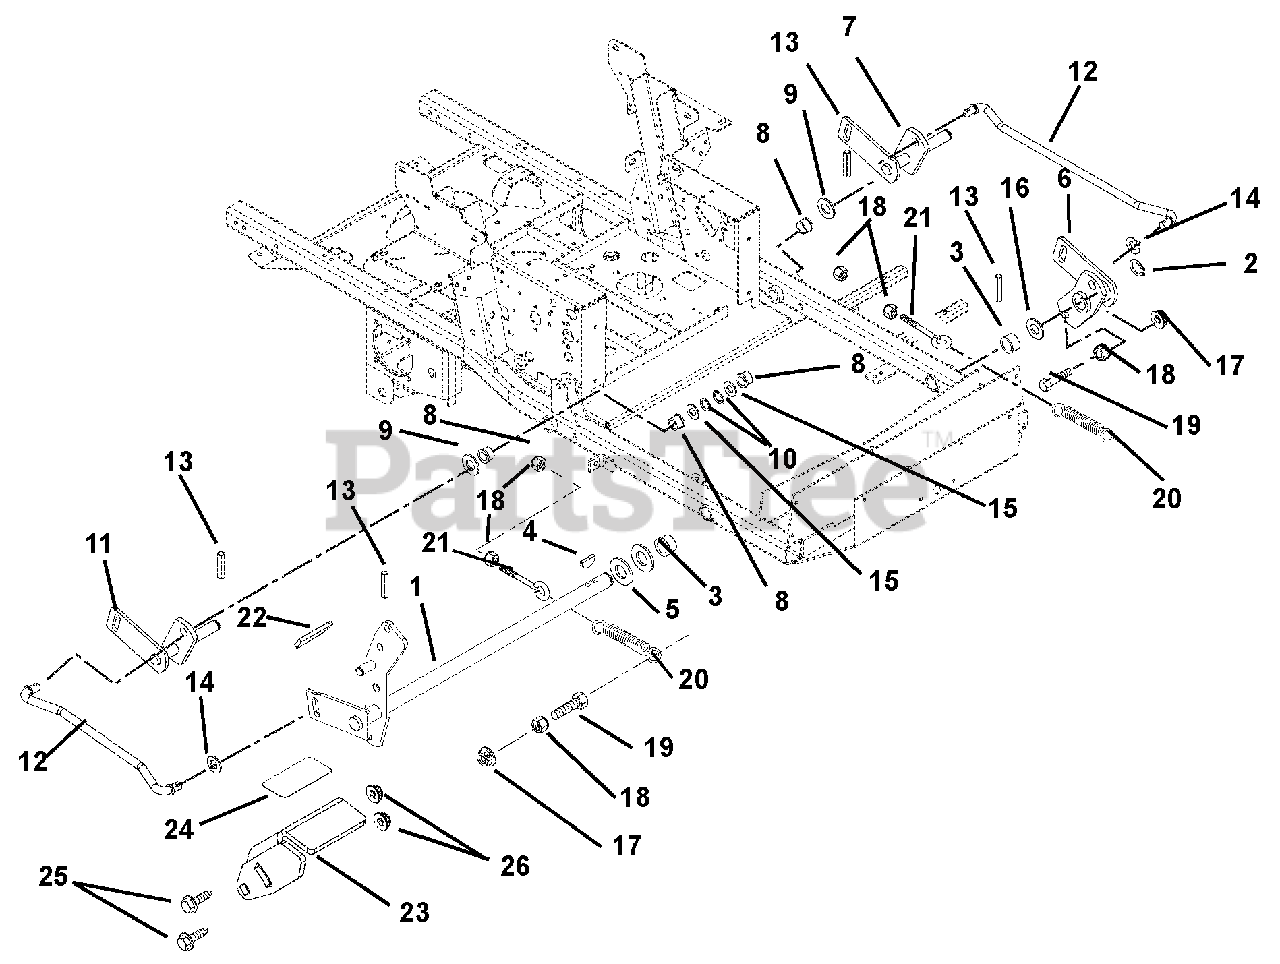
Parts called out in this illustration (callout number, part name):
1	Lift, Mechanical Mower (992210, 212)
2	Ring, Retaining External 1.00 x .078
3	Bushing, 1.00 x 1.12 x .75 x 1.375
4	Key, Woodruff .25 x 1.00
5	Washer, Flat Steel 1.062 x 2.00 x .134
6	Weldment, Lift Arm Front
7	Weldment, Left Hand Rear Lift Arm
8	Bushing, Flange Nylon .762 x 1.00 x .58 x 1.48
9	Washer, Hardened Steel .758 x 1.23 x .031
10	Ring, Retaining External .689 x .077
11	Weldment, Right Hand Rear Lift Arm
12	Rod, Lift Assist
13	Pin, Roll .250 x 1.25 Stainless Steel
14	Washer, Flat-Steel .630 x 1.25 x .062
15	Washer, Flat Steel .812 x 1.50 x .135
16	Washer, Hardened Thrust 1.00 x 1.55 x .03
17	Nut, Locking Top Flange .38-16 (992210, 212)
18	Nut, Hex .38-16 (992210, 212)
19	Bolt, Hex .38-16 x 1.75 Grade 5 (992210, 212)
20	Spring, Tension .162 x 1.25 x 8.25 (992210, 212)
21	Bolt, Eye .375-16 x 2.50 (992210, 212)
22	Grip, Foot Pedal (992210, 212)
23	Pedal, Foot Lift Adjustable (992210, 212)
24	Grip, Foot Pedal (992210, 212)
25	Bolt, Round Hd. Square Neck .50-13 x 1.50 (992210, 212)
26	Nut, Lock Nyloc Flange .50-13 (992210, 212)
